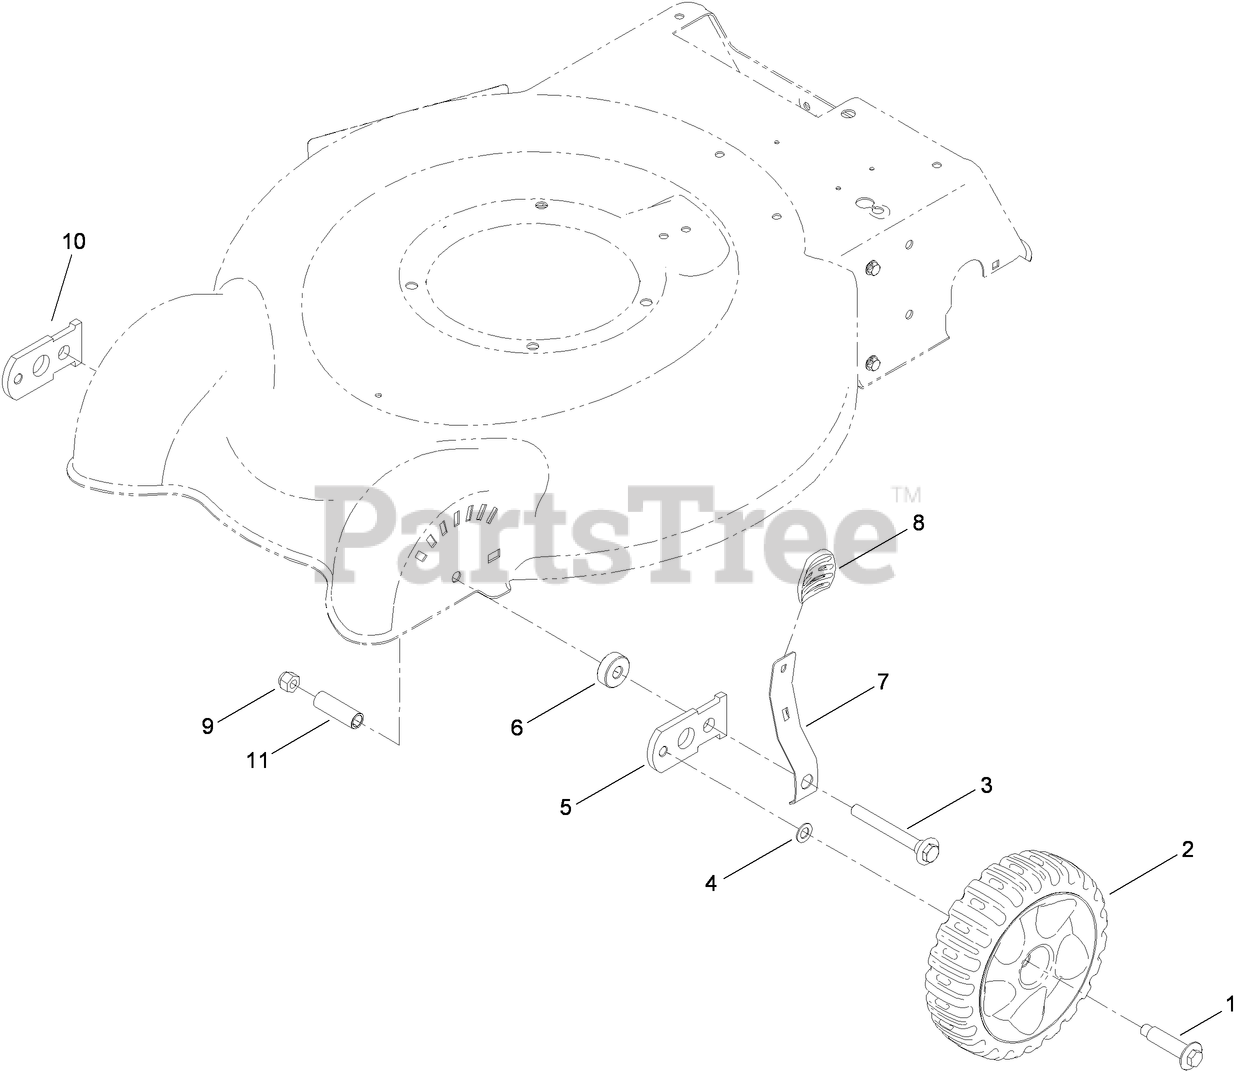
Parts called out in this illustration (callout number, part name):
1	BOLT-SHOULDER
2	7 INCH WHEEL AND TIRE ASM
3	BOLT-SHOULDER
4	WASHER
5	ARM-PIVOT, RH
6	SPACER-ARM, PIVOT
7	ARM-SPRING, FRONT
8	KNOB-LEVER, HOC
9	NUT-LOCK, NI
10	ARM-PIVOT, LH
11	SPACER-BAFFLE, FRONT
